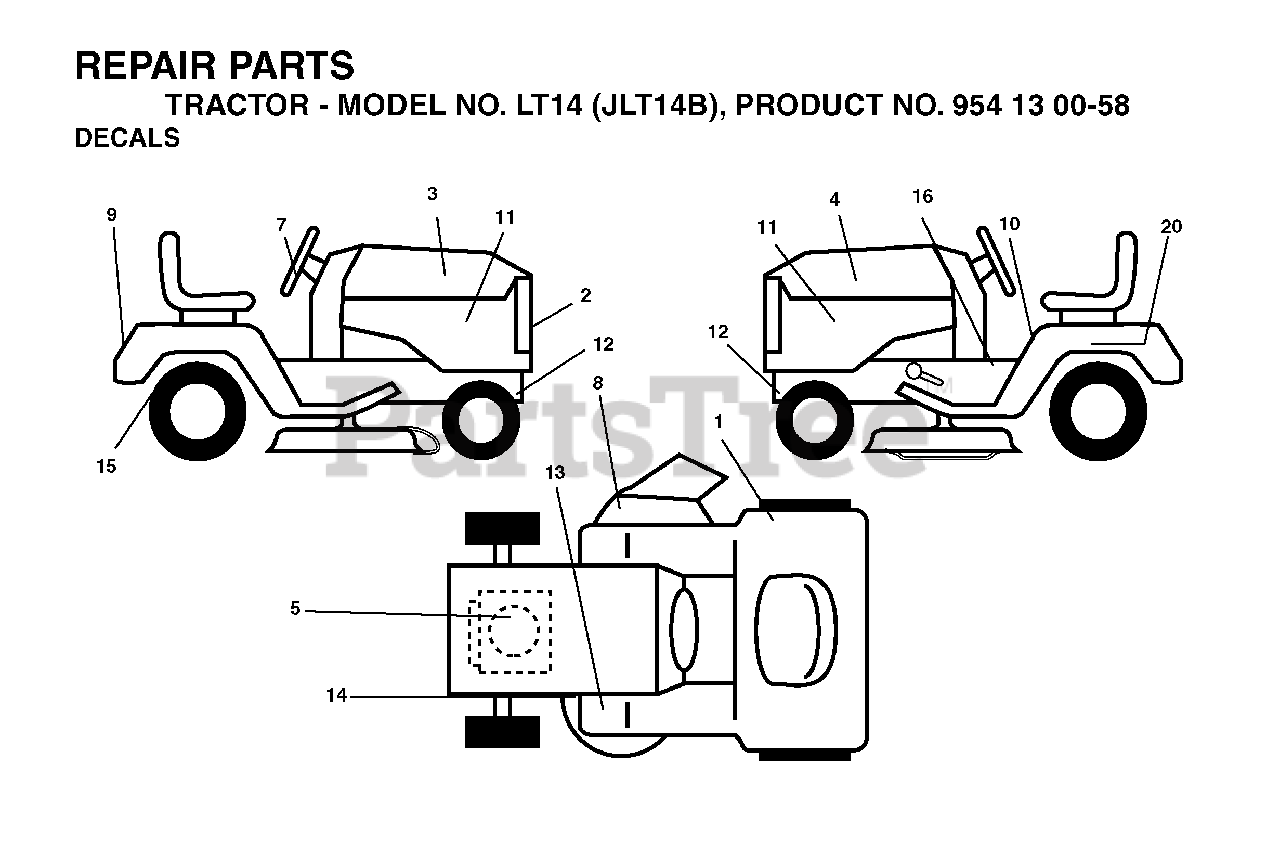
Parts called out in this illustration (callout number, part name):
8	DECAL.INTERNATIONL.CUTFINGER
10	DECAL READ OWNER'S MAN SYMS
14	DECAL V-BELT SCHEMATIC
16	DECAL PARK BRAKE
20	DECAL BTRY SYMBOLS
